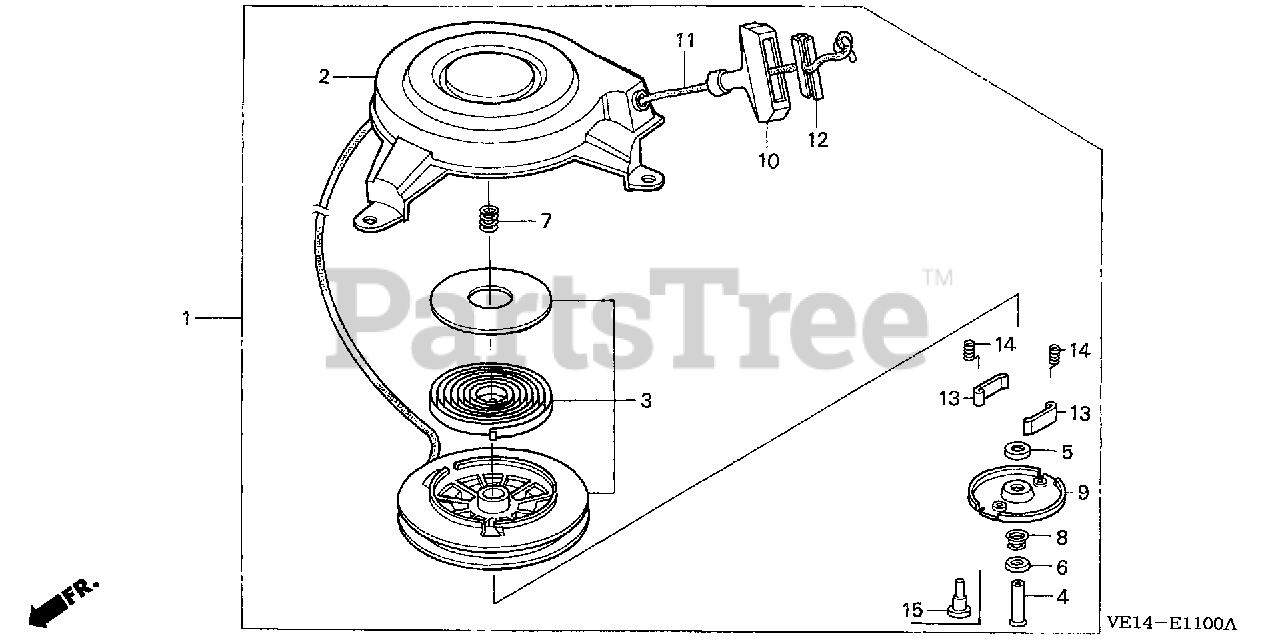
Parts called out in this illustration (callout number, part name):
1	STARTER ASSY., RECOIL
2	HOUSING ASSY. (NA USE ALT:28400-ZG9-803)
3	PULLEY & SPRING ASSY.
4	PIN, CENTER
5	PLATE A, FRICTION
6	PLATE B, FRICTION (NOT AVAILABLE)
8	SPRING, FRICTION
11	ROPE, RECOIL STARTER
12	HANDLE, REINFORCEMENT
14	SPRING, DOG
